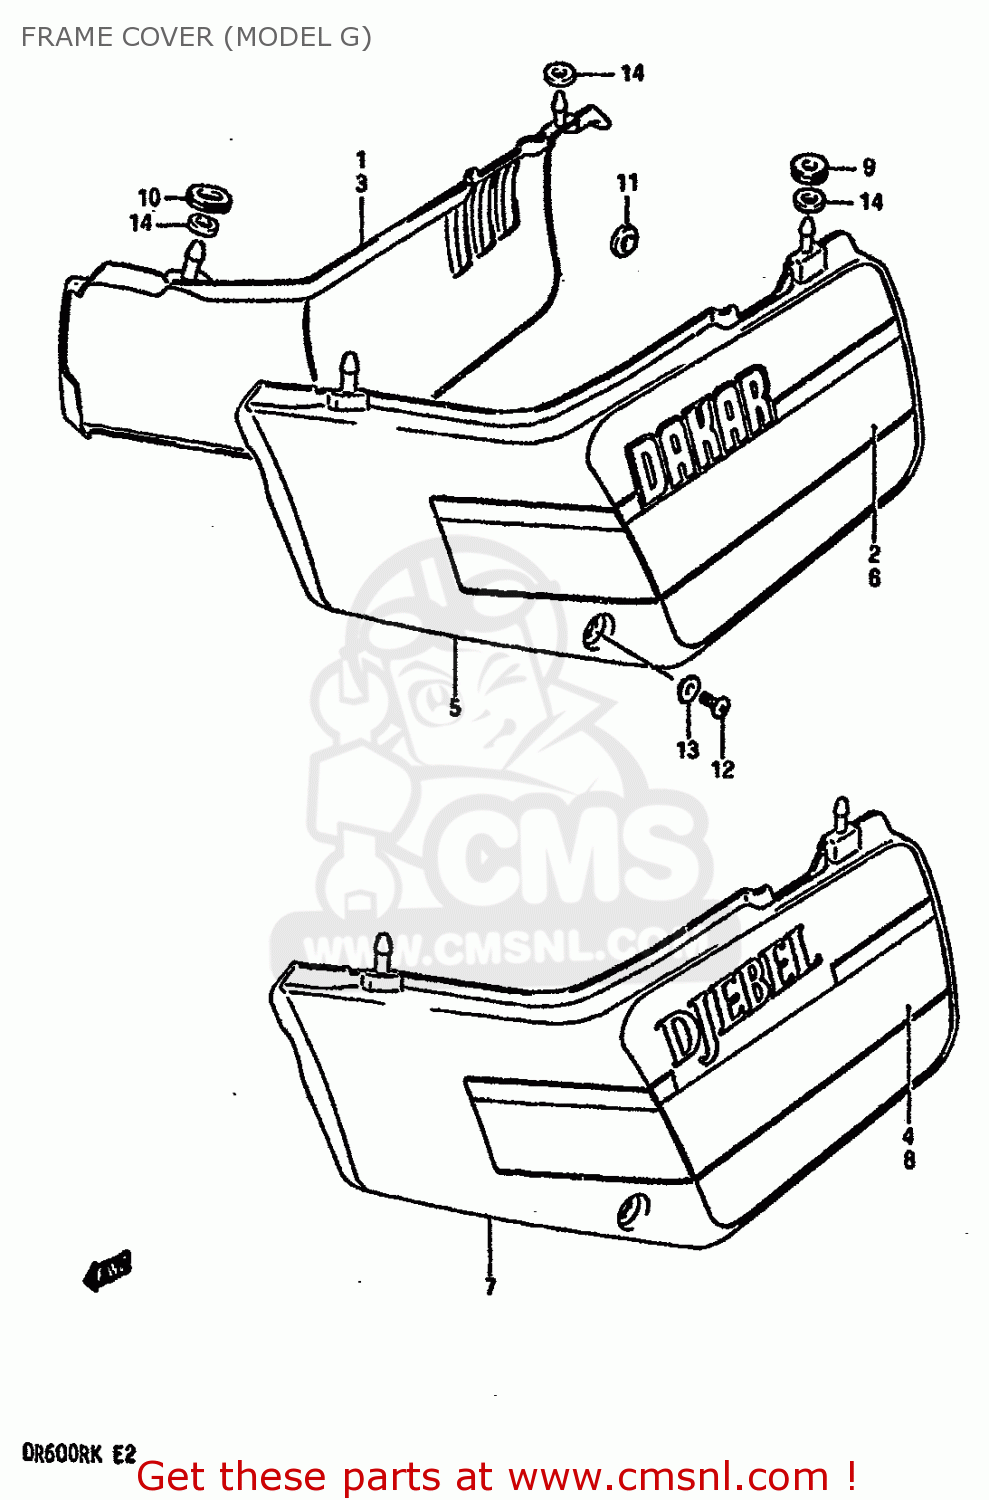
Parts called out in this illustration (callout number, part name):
1	COVER, FRAME RH (WHITE)
2	TAPE SET, FRAME COVER RH
3	COVER,FRAME RH (WHITE)
4	TAPE SET,SIDE COVER RH
5	COVER, FRAME LH (WHITE)
6	TAPE SET, FRAME COVER LH
7	COVER,FRAME LH (WHITE)
8	TAPE SET,SIDE COVER LH
9	CUSHION
10	CUSHION
11	CUSHION
12	SCREW 6X12
13	WASHER
14	CUSHION,SIDE COVER BOSS
